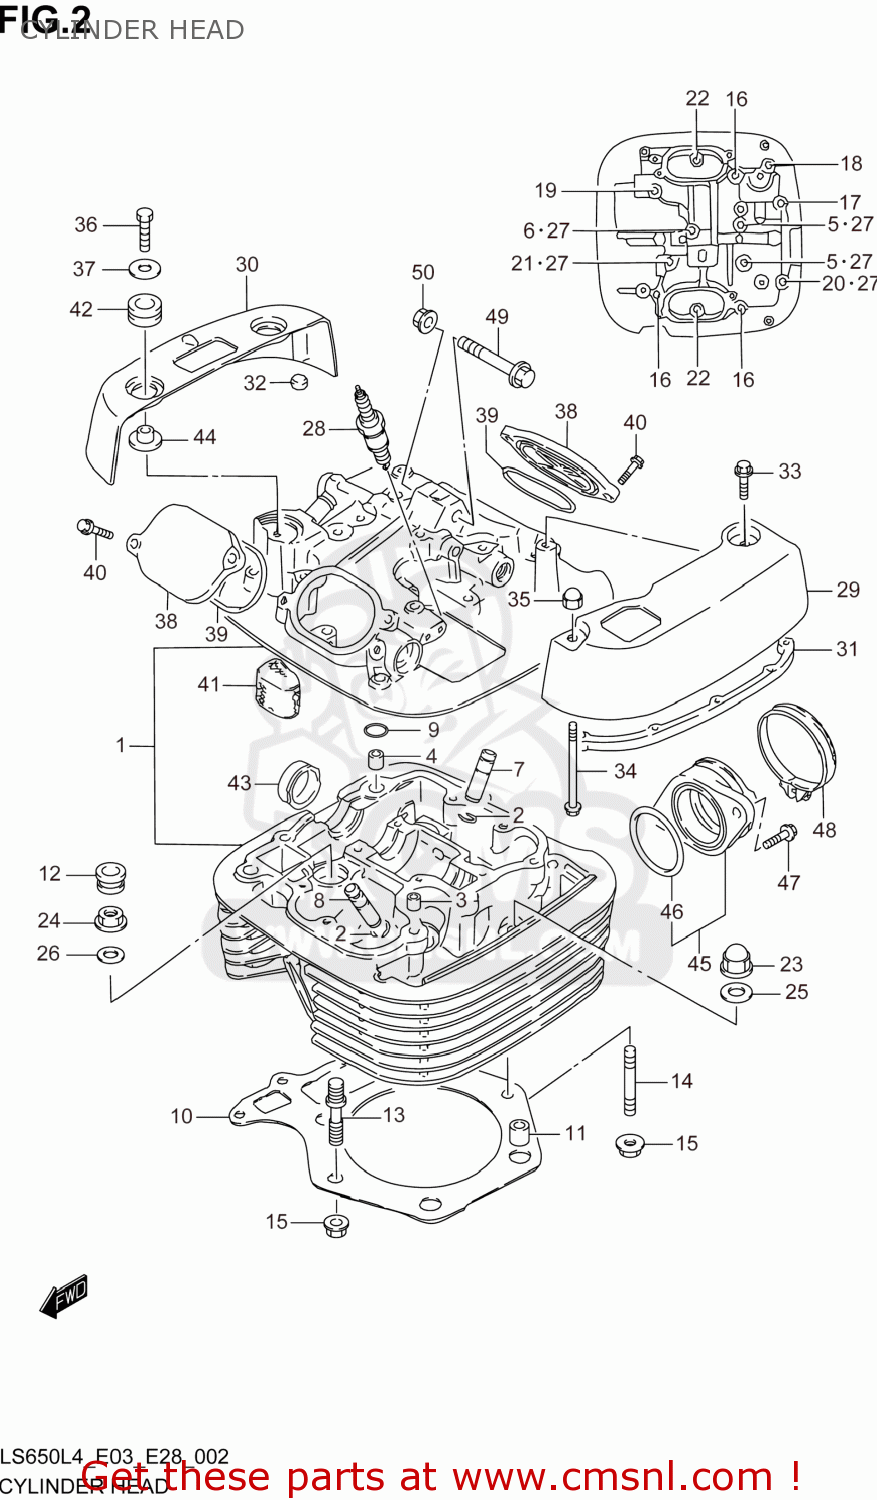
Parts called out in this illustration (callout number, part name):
1	HEAD ASSY,CYLINDER
2	RING,SNAP
3	PIN(6.2X8X11)
4	PIN(11X14)
5	BOLT(6X60)
6	BOLT(6X70)
7	GUIDE,VALVE
8	GUIDE,VALVE
9	O RING,CYL HEAD COVER
10	GASKET,CYLINDER HEAD (NAS)
11	PIN
12	CAP,CYLINDER HEAD SEAL
13	BOLT,STUD
14	BOLT,STUD(8X31)
15	NUT
16	BOLT(6X39)
17	BOLT(6X125)
18	BOLT(6X115)
19	BOLT(6X60)
20	BOLT(6X130)
21	BOLT(6X55)
22	BOLT
23	NUT
24	NUT
25	GASKET(10.2X20X2).3 (NAS)
26	GASKET(10.2X20X2).3 (NAS)
27	GASKET(5.8X13X1.2) (NAS)
28	PLUG,SPARK(DPR8EA-9)
29	CAP,HEAD COVER,L
30	CAP,CYLINDER HEAD COVER,R
31	CUSHION,HEAD COVER CAP,L
32	CUSHION,R CAP
33	BOLT
34	BOLT
35	NUT
36	BOLT
37	WASHER(6.5X24X1.6)
38	CAP,INSPECTION
39	O RING(D:2.4,ID:23)
40	BOLT
41	SEPARATOR,OIL BREATHER COVER
42	CUSHION
43	PLUG(OD:30)
44	BUSH
45	PIPE ASSY,INTAKE
46	O RING(D:2.4,ID:45.7)
47	SCREW
48	CLAMP
49	BOLT(8X55)
50	NUT
